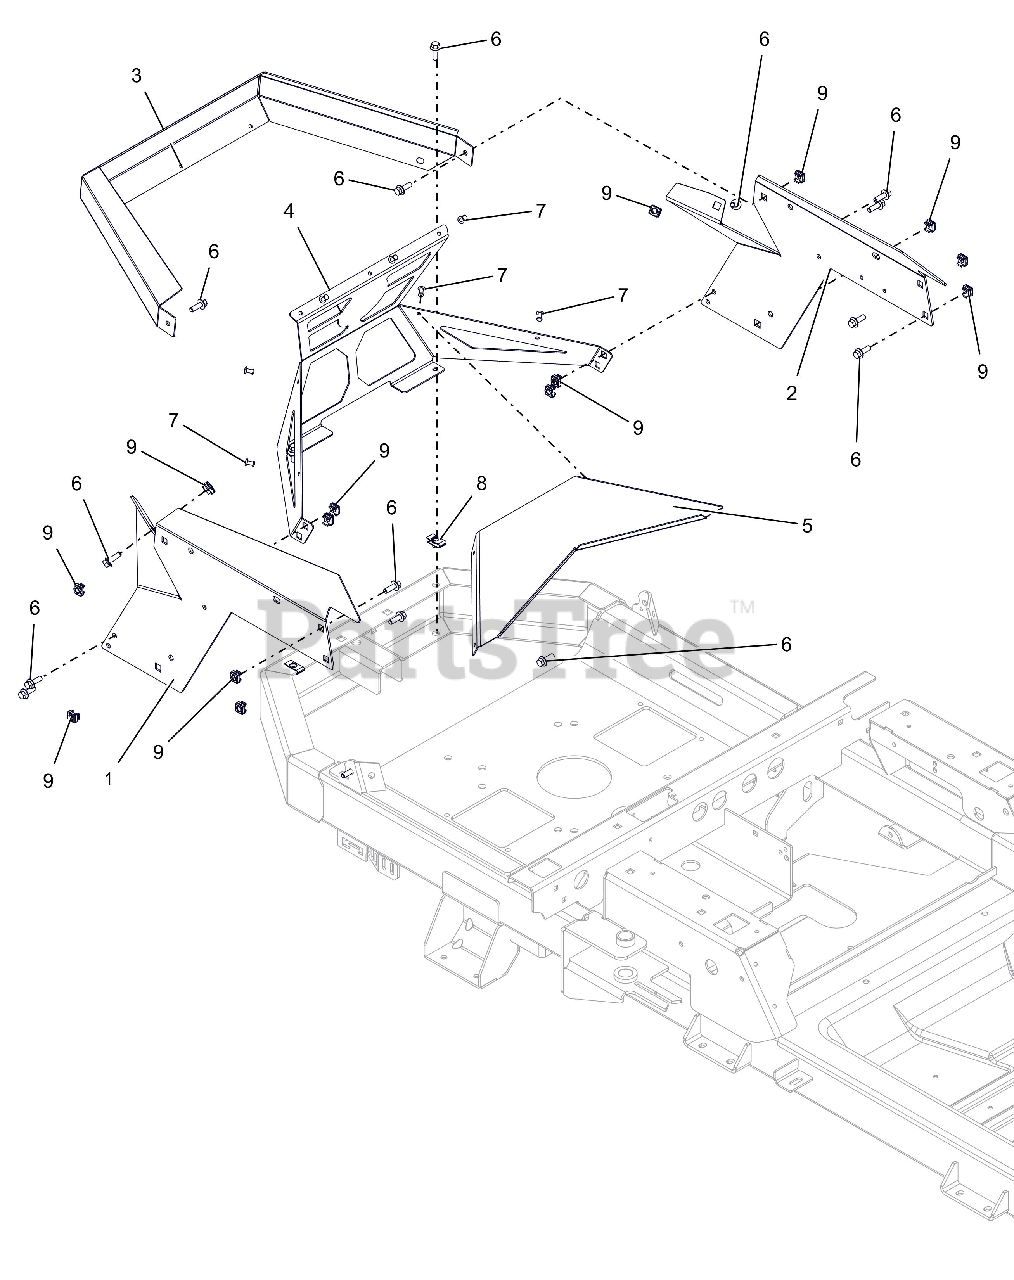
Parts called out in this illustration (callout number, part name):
1	PANEL, RIGHT REAR FENDER MOUNT
2	PANEL, LEFT REAR FENDER MOUNT
3	GUARD, ENGINE WRAP
4	GUARD, ENGINE
5	BAFFLE,ENGINE WRAP
6	BLT,HEX-FLG .25-20X.75 G5 BFP
7	RIVET, #66 STEEL POP PD BLACK
8	NUT-RTNR .25-20X.56
9	NUT RETNR .25-20
